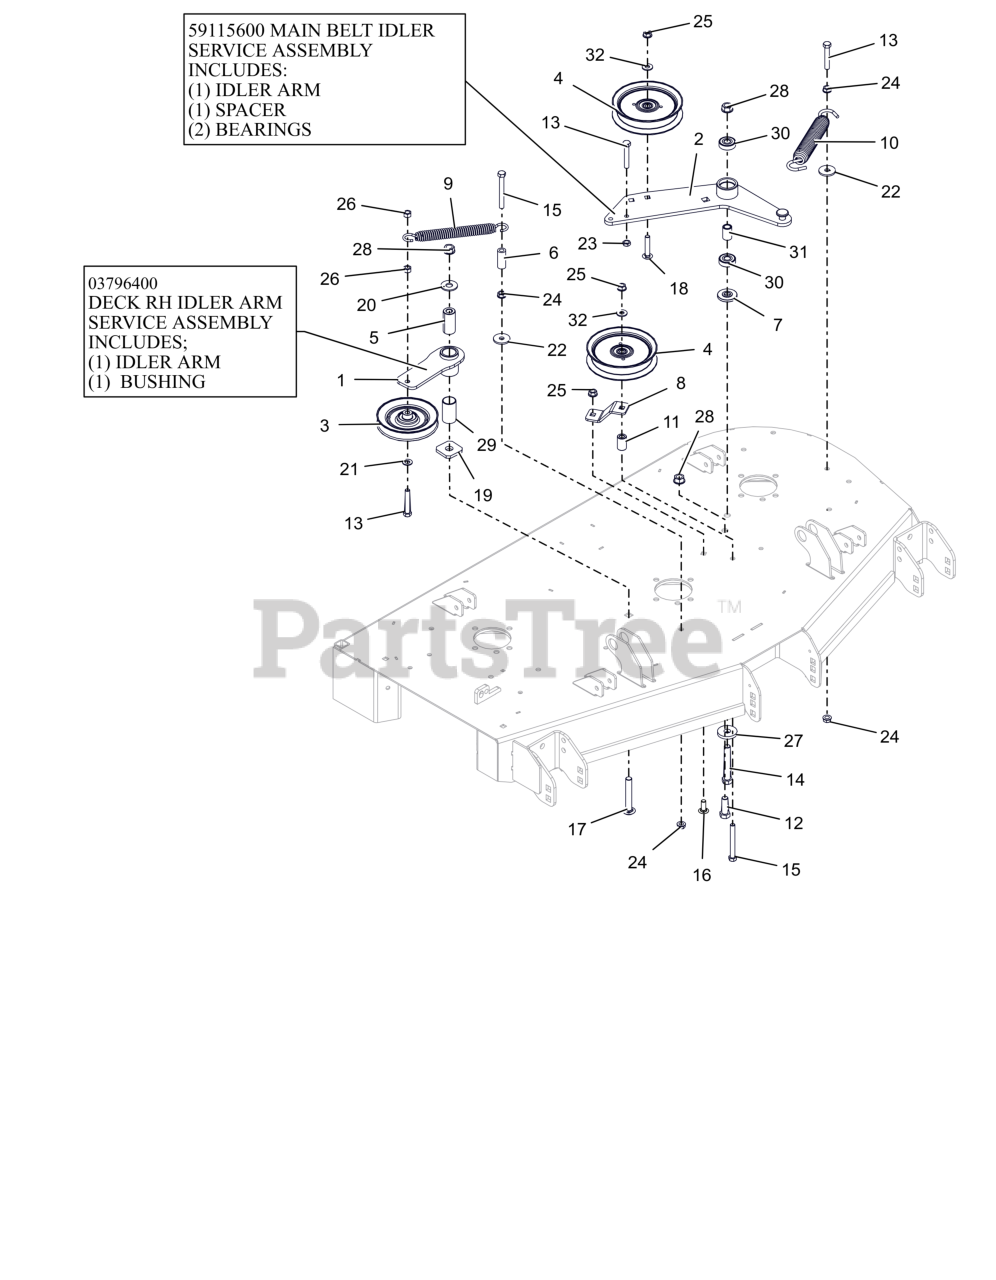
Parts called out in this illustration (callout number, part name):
1	WMT, IDLER ARM - BLACK
1	ASM, IDLER ARM (DECK)
2	WLDMT, DECK PTO IDLR ARM
2	ASSEMBLY, MAIN BELT IDLER
3	IDLER, V-5.00"
4	IDLER, FLAT 5.00"
5	BSHG, SPCR .502X.997X2.03 PM
6	HOSE, .38 X 1.65
7	SPACER, IDLER ARM
8	PTO FIXED IDLER MTG BRKT-ORG
9	SPRING, EXTENSION
10	SPRING, EXTENSION
11	BUSHING, SLV .380X.750X1.190
12	BLT,HEX .50-13X1.50 G5 ZCC
13	BLT,HEX .38-16X2.25 G5 ZCC
14	BLT,HEX .50-13X3.25 G5 ZCC
15	BLT, HEX .38-16X3.25 G5 ZCC
16	BLT,RHSSN .38-16X1.00 G5 ZCC
17	BTL,RHSSN .500-13 X 3.25 G5 ZCC
18	BLT,RHSSN.375-16X2.00 G5 ZCC
19	WSHR-FLT .640X1.75X.250
20	WSHR,FLT .563X1.375X.109 ZCC
21	WSHR,FLT .406X.812X.065 ZCC
22	WSHR,FLT .406X1.375X.135 ZCC
23	NUT-JAM .375-16 G2 ZCC
24	NUT, SPNLK-FLG .38-16 G5 ZCC
25	NUT-LK-CTR-FLG .375-16 GF ZCC
26	NUT-LK-CTR .38-16 ZC120
27	WSHR-FL-STL 0.557X1.625X0.25 ZCC
28	NUT-LK-CTR-FLG .500-13 GG ZCC
29	BSHG, 1.00X1.125X1.937
30	BRG-BALL .500X1.38X.437
31	SPACER .510 X .75 X 1.1485
32	WSHR,FLT .375X.875X.083 ZCC
